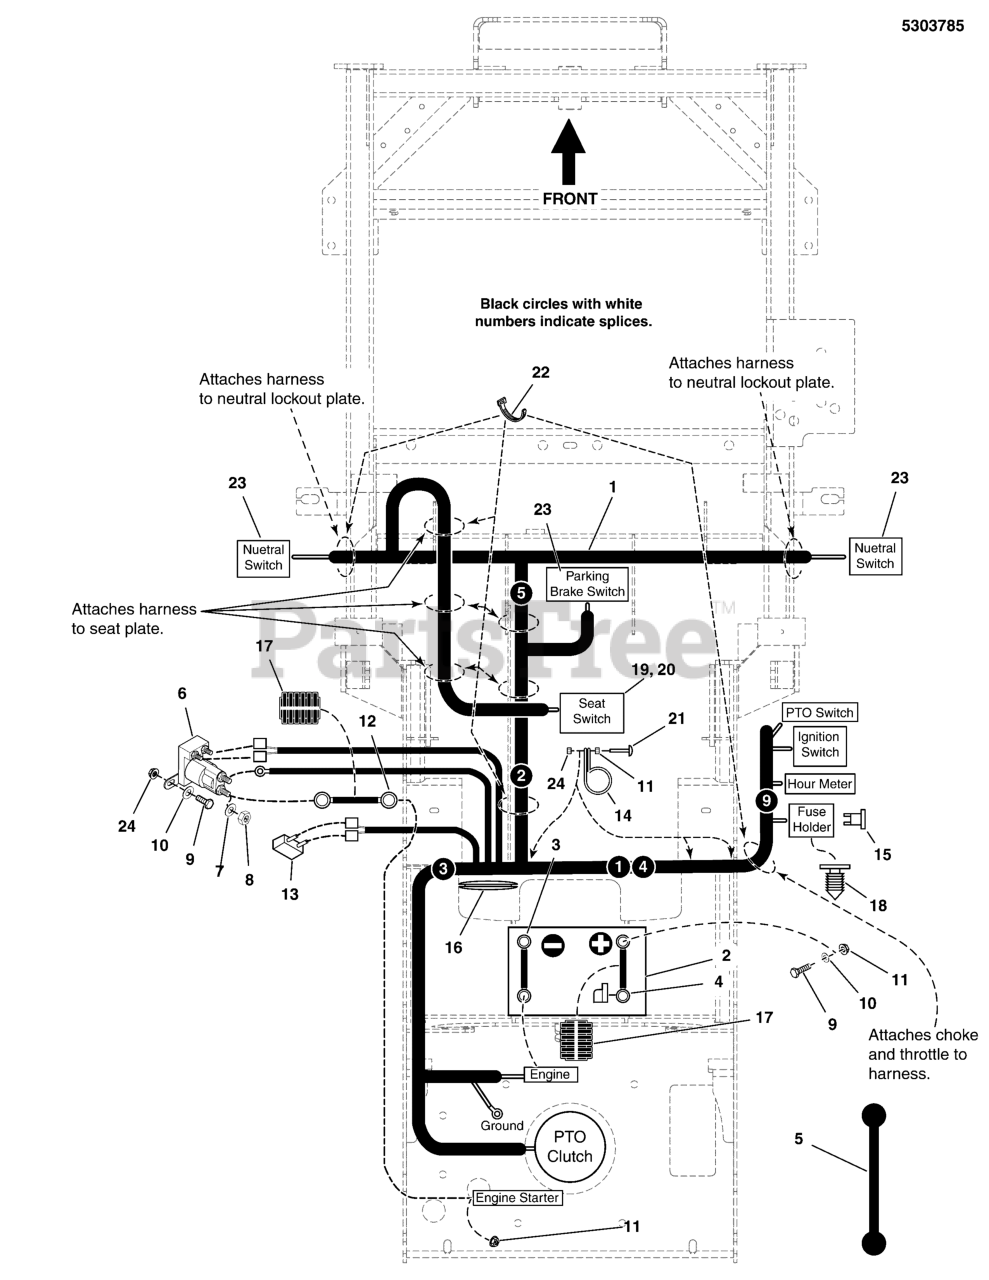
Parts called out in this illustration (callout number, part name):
1	WIRE HARNESS, C TURF,WARNER, S125XT
2	BATTERY, WET ( BCIU1, 340 CCA)
3	BATTERY CABLE, NEGATIVE, 14"
4	BATTERY CABLE, POSITIVE, 22
5	STRAP-BLACK RUBB
6	SOLENOID-4 POLE 12 VOLT DC (TROMBETTA)
7	WASHER, 5/16 LIGHT LOCK
8	NUT, 5/16-24 JAM
9	BOLT, 1/4-20 X 3/4 GD5 YZ
10	WASHER, 1/4 SAE
11	NUT, 1/4-20 HEX SERR. FLANGE
12	BATTERY CABLE, POSITIVE, 22
13	BREAKER-CIRCUIT 12VOLT 20AMPS W/TAB
14	CLAMP, VINYL INSULATED
15	FUSE, ATO 15 AMP
16	GROMMET, 1-1/2" ID FOR 1/4" METAL
17	WIRE LOOM, 3/8 ID X 18 IN
18	FIR TREE MOUNT, PACKARD
19	SWITCH, NC, W/ BOLT-IN BASE
20	SWITCH, NC, W/ TWIST-IN BASE
22	TIE, SELF-LOCKING, 12"
23	SWITCH, DP NO/NC SNAP-IN
24	NUT, 1/4-20 HEX NYLOCK FLANGE
